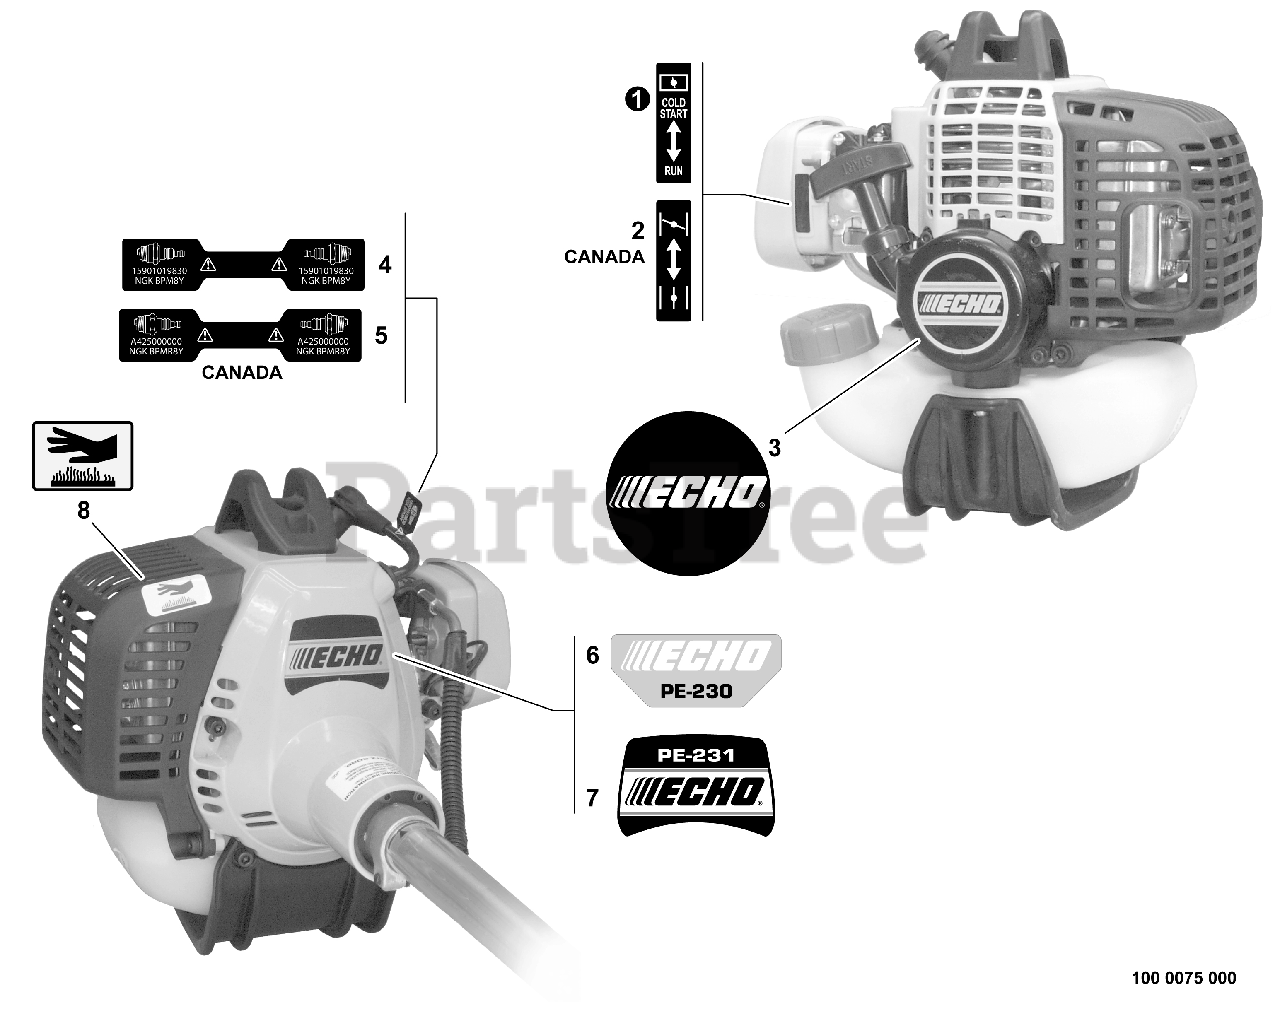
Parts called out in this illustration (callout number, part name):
1	LABEL - CHOKE
2	LABEL - CHOKE
3	LABEL - ECHO
4	LABEL - SPARK PLUG -- BPM-8Y
5	LABEL - SPARK PLUG -- BPMR-8Y
6	LABEL - MODEL PE-230
7	LABEL - MODEL PE-231
8	LABEL - HOT SURFACE
